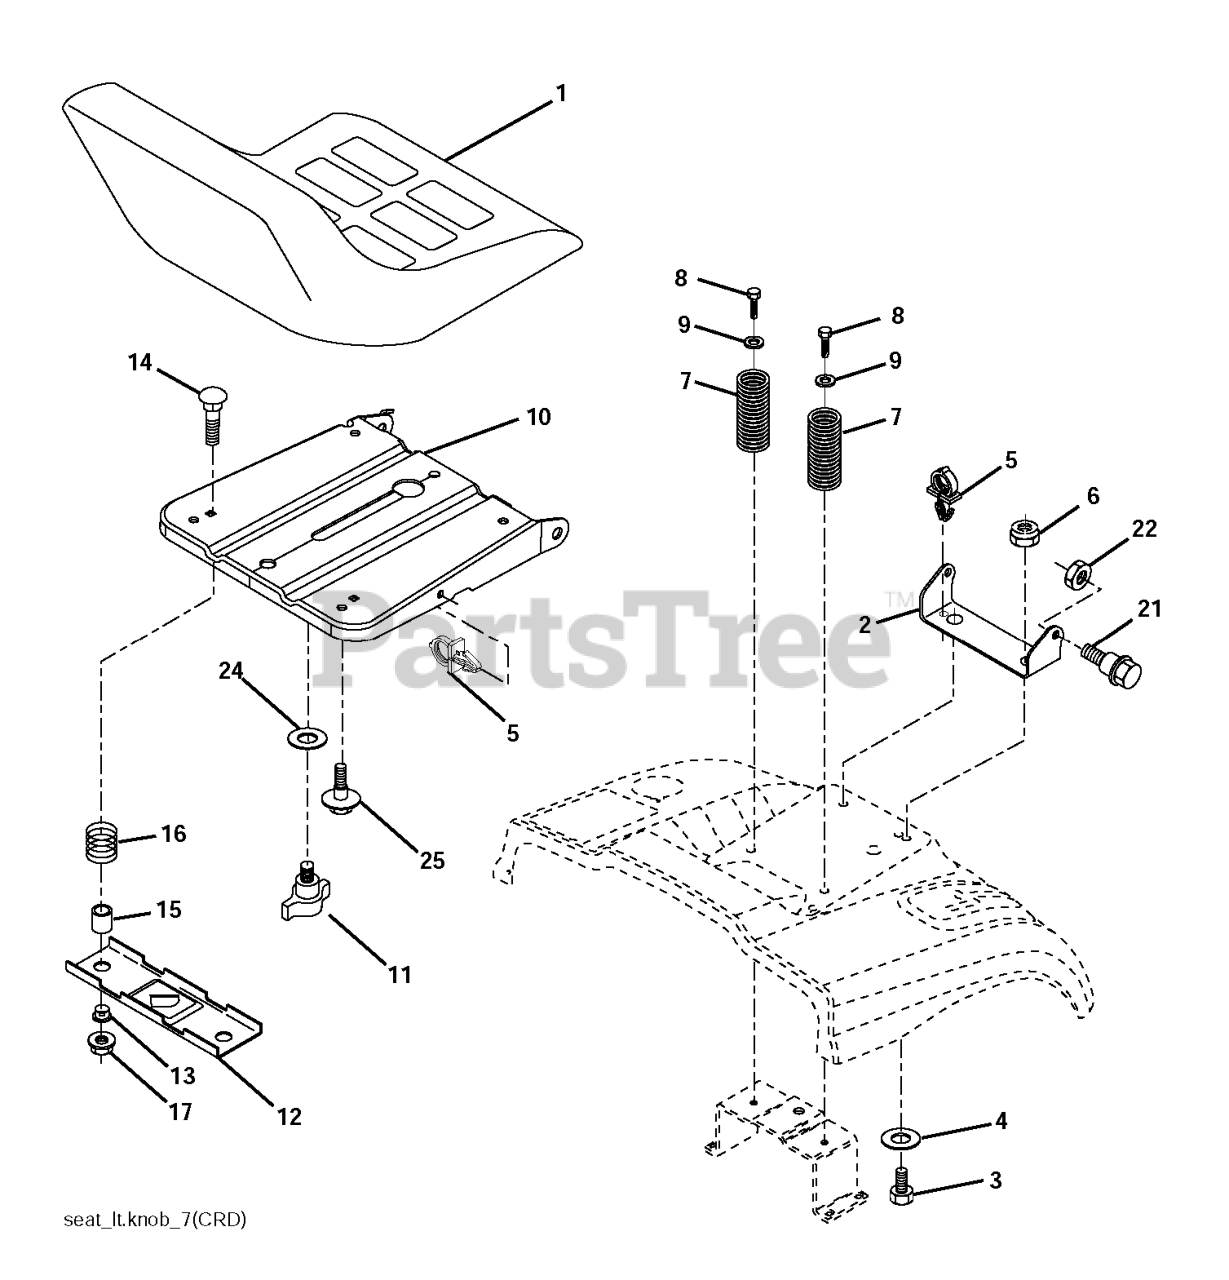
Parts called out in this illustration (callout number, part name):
1	RP SEAT
2	SEAT PIVOT BRKT
3	BOLT, HEX 3/8-16X1
6	NUT
7	SPRING COMPRESSION
8	SCREW 3/8-16X1
9	WASHER
10	PAN.ASM.SEAT.1SLOT
11	KNOB.SEAT.ADJ.WINGNUT
12	BRKT.MNTNG.SWITCH.SEAT.BLACK
14	BOLT.ROUND.HEAD.SQUARE.NECK
15	SPACER SPLIT 28X.96
17	NUT T
21	BOLT.SHOULDER.5/16-18
22	NUT.71038.31-18.HEX.NYLOCK
25	BOLT,SHOULD
